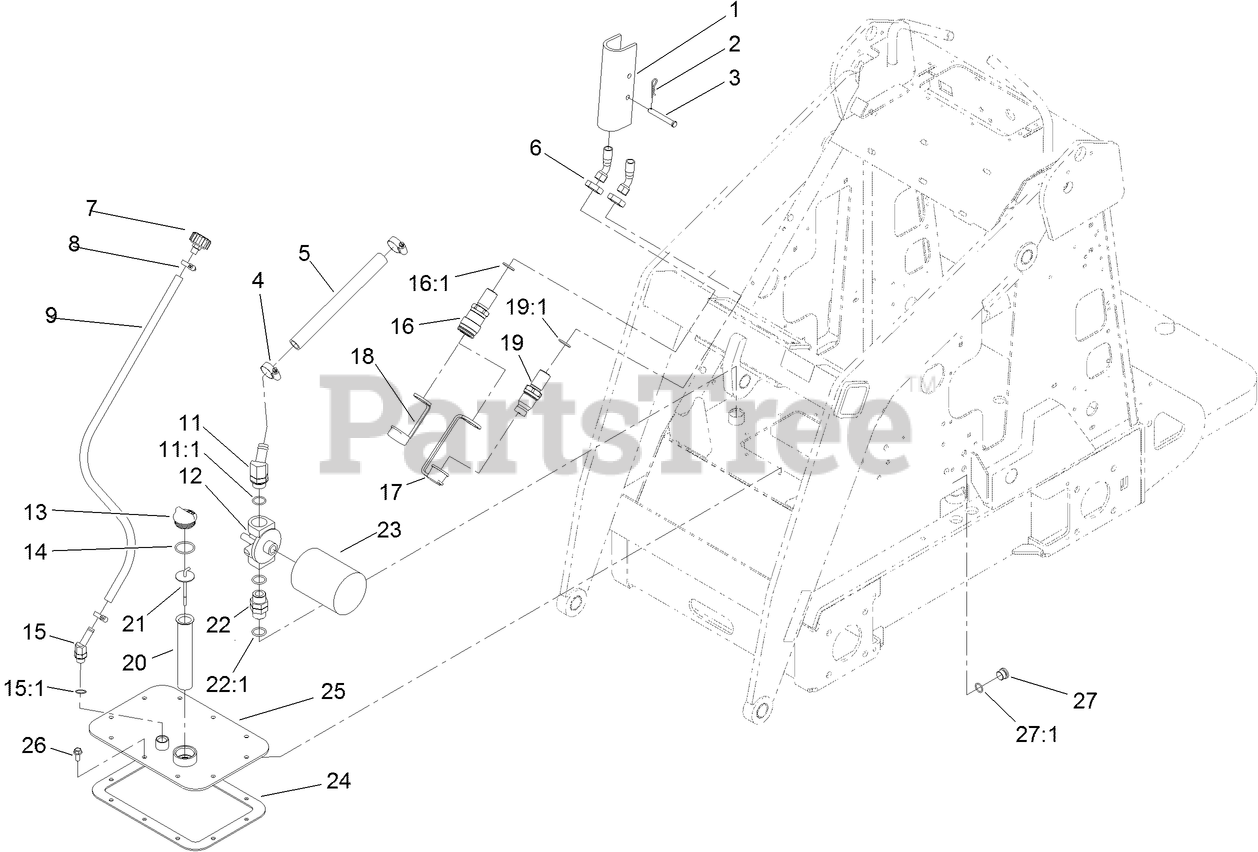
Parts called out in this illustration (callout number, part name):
1	LOCK-CYLINDER
2	PIN-HAIR
3	PIN-CLEVIS
4	CLAMP-HOSE
5	HOSE-HYD, SUCTION, HI
6	NUT-LOCK, BULKHEAD
7	BREATHER
8	CLAMP-HOSE
9	HOSE-VENT
11	ELBOW-45 DEG
11:1	O-RING
12	HEAD-FILTER
13	PLUG-PLASTIC
14	O-RING
15	FITTING-HYD, 45 DEG
15:1	O-RING
16	BULKHEAD COUPLER ASM
16:1	O-RING
17	CAP-DUST, NIPPLE
18	CAP-DUST, COUPLER
19	BULKHEAD NIPPLE ASM
19:1	O-RING
20	FILTER-SCREEN
21	DIPSTICK-OIL
22	FITTING-THREAD, STRAIGHT
22:1	O-RING
23	FILTER-OIL, TRANSMISSION
24	GASKET-COVER
26	SCREW
27	PLUG-HEX
27:1	O-RING
